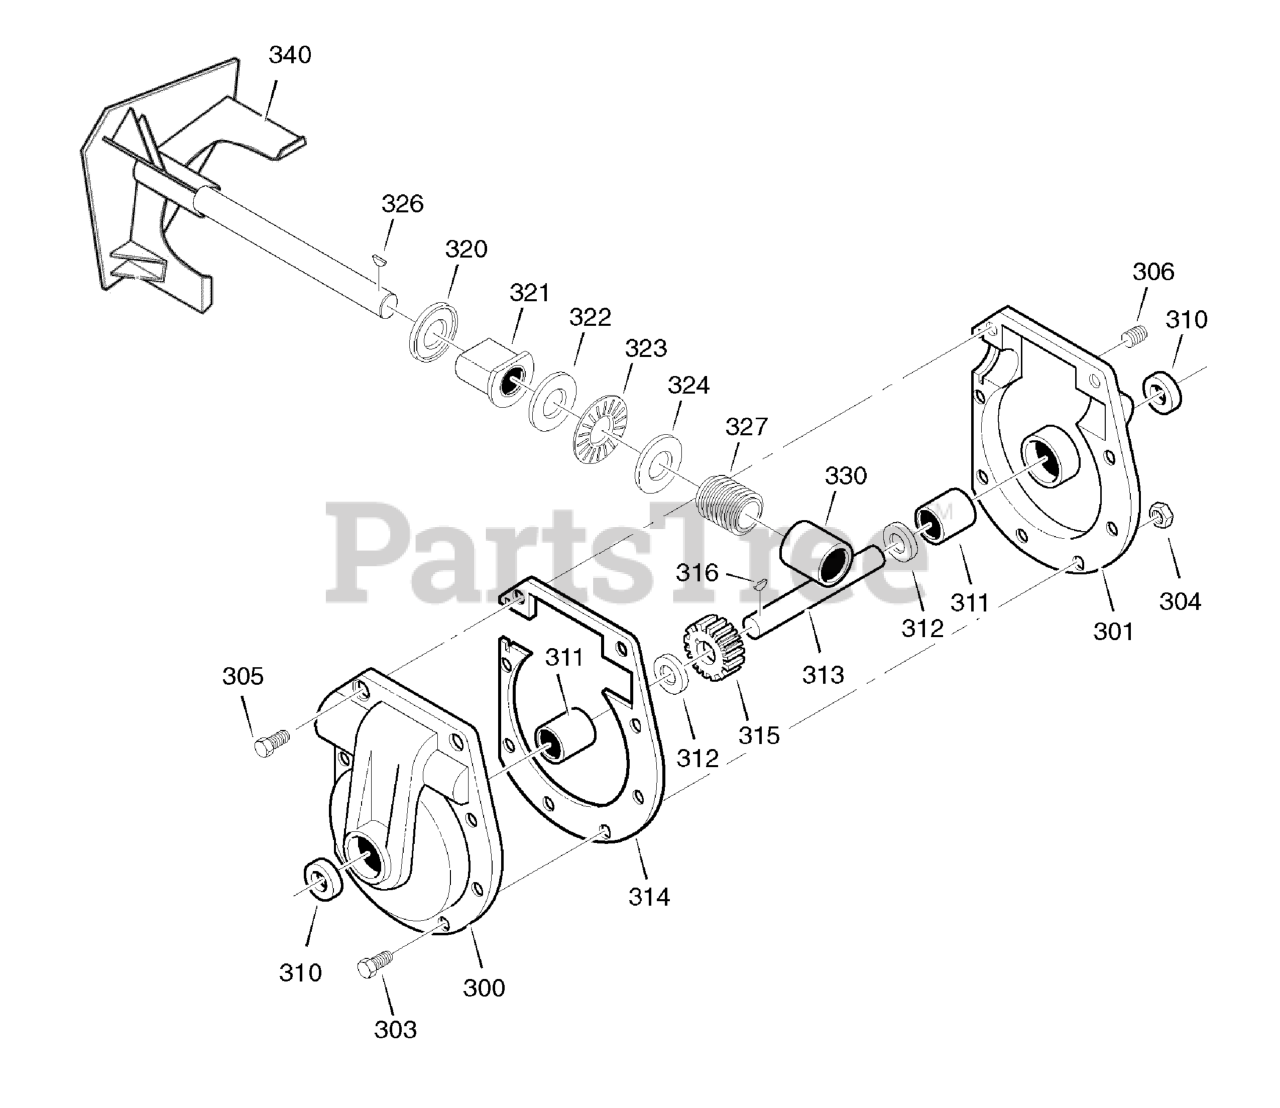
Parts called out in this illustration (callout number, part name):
300	CASE, GEAR, RH
301	CASE, GEAR, LH
303	SCREW, 5/16-24 x 1.00
304	NUT, 5/16-24
305	SCREW, 5/16-24 x 1.50
306	PLUG, PIPE 0.25-18
310	SEAL, OIL
311	BEARING, SLEEVE
312	WASHER, FLAT
313	SHAFT, AUGER OUTPUT
314	GASKET, GEAR BOX
315	WORM GEAR
316	KEY, WOODRUFF #91
320	RING, QUAD 0.924 ID
321	BEARING, FLANGE
322	WASHER, FLAT
323	BEARING, ROLLER
324	WASHER, FLAT
330	BEARING, SLEEVE
340	IMPELLER
